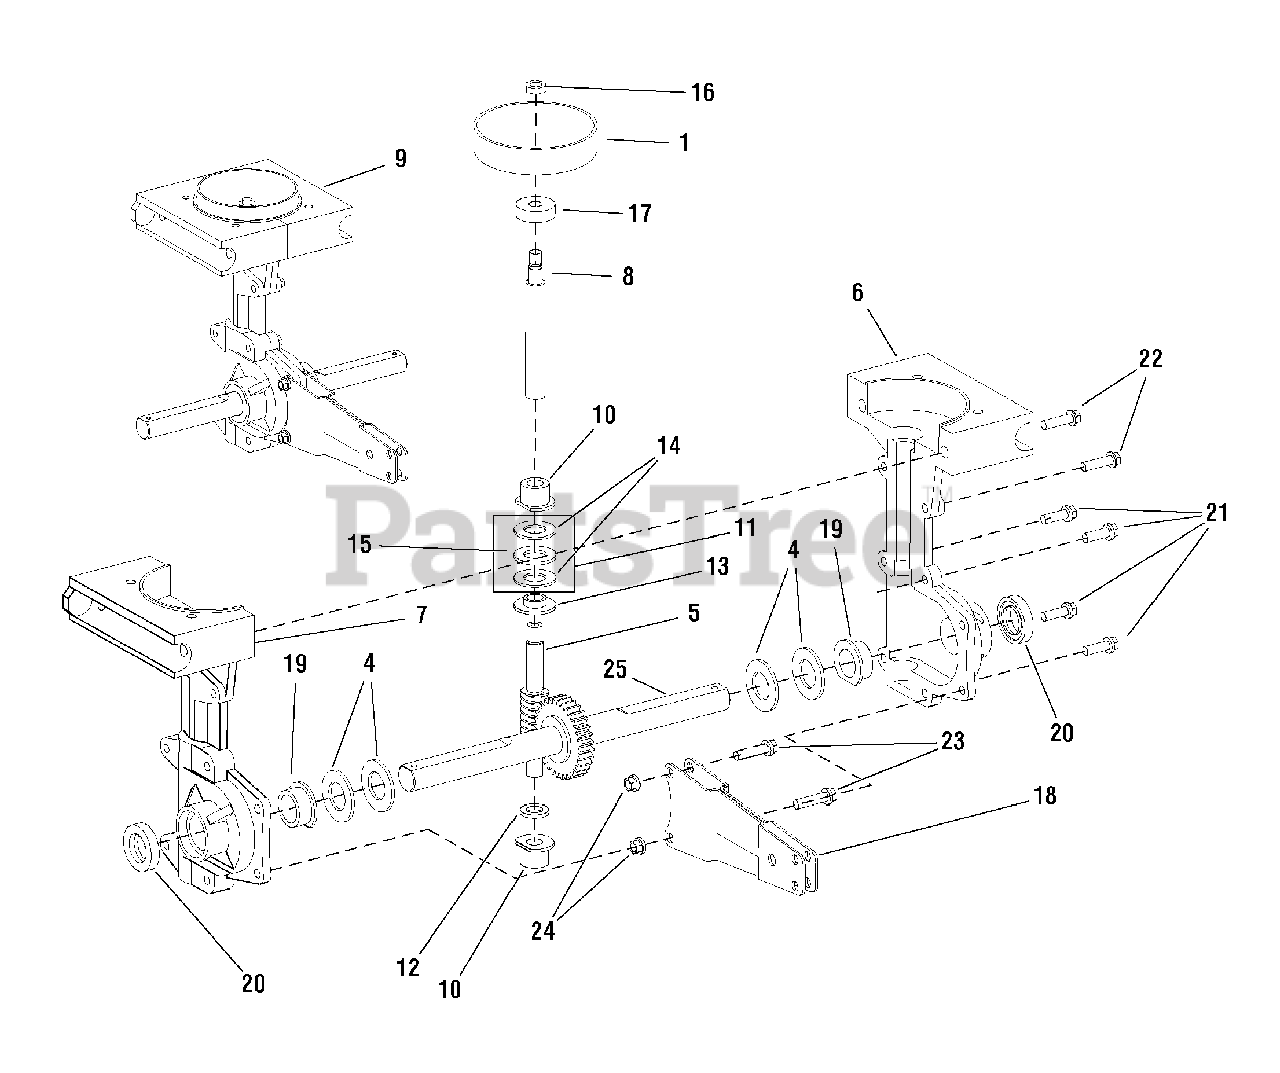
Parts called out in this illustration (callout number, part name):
1	CLUTCH DRUM
4	SHIM, Tine Shaft
5	WORM SPUD
6	TRANSMISSION CASTING, Right
7	TRANSMISSION CASTING, Left
8	DRIVE SHAFT
9	TRANSMISSION ASSEMBLY
10	BUSHING, Drive Shaft
11	THRUST BEARING ASSEMBLY
12	SPACER, Bushing
13	REDUCER, Thrust Bearing
14	WASHER, Thrust
15	WASHER, Thrust Bearing Cage
16	NUT, Jam, M8
17	BALL BEARING, 9mm
18	MOUNT, Arm Wheel / Drag Stake
19	BUSHING, Tine Shaft
20	SEAL, Tine Shaft
21	BOLT, Hex Head Flange, M6 x 1 x 18mm
22	BOLT, Hex Head Flange, M6 x 1 x 22mm
23	BOLT, Hex Head Flange, M6 x 1 x 24mm
24	NUT, Hex Flange, M6
25	TINE GEAR & SHAFT ASSEMBLY
26	* TINE SHAFT
27	* GEAR, Tine Shaft
